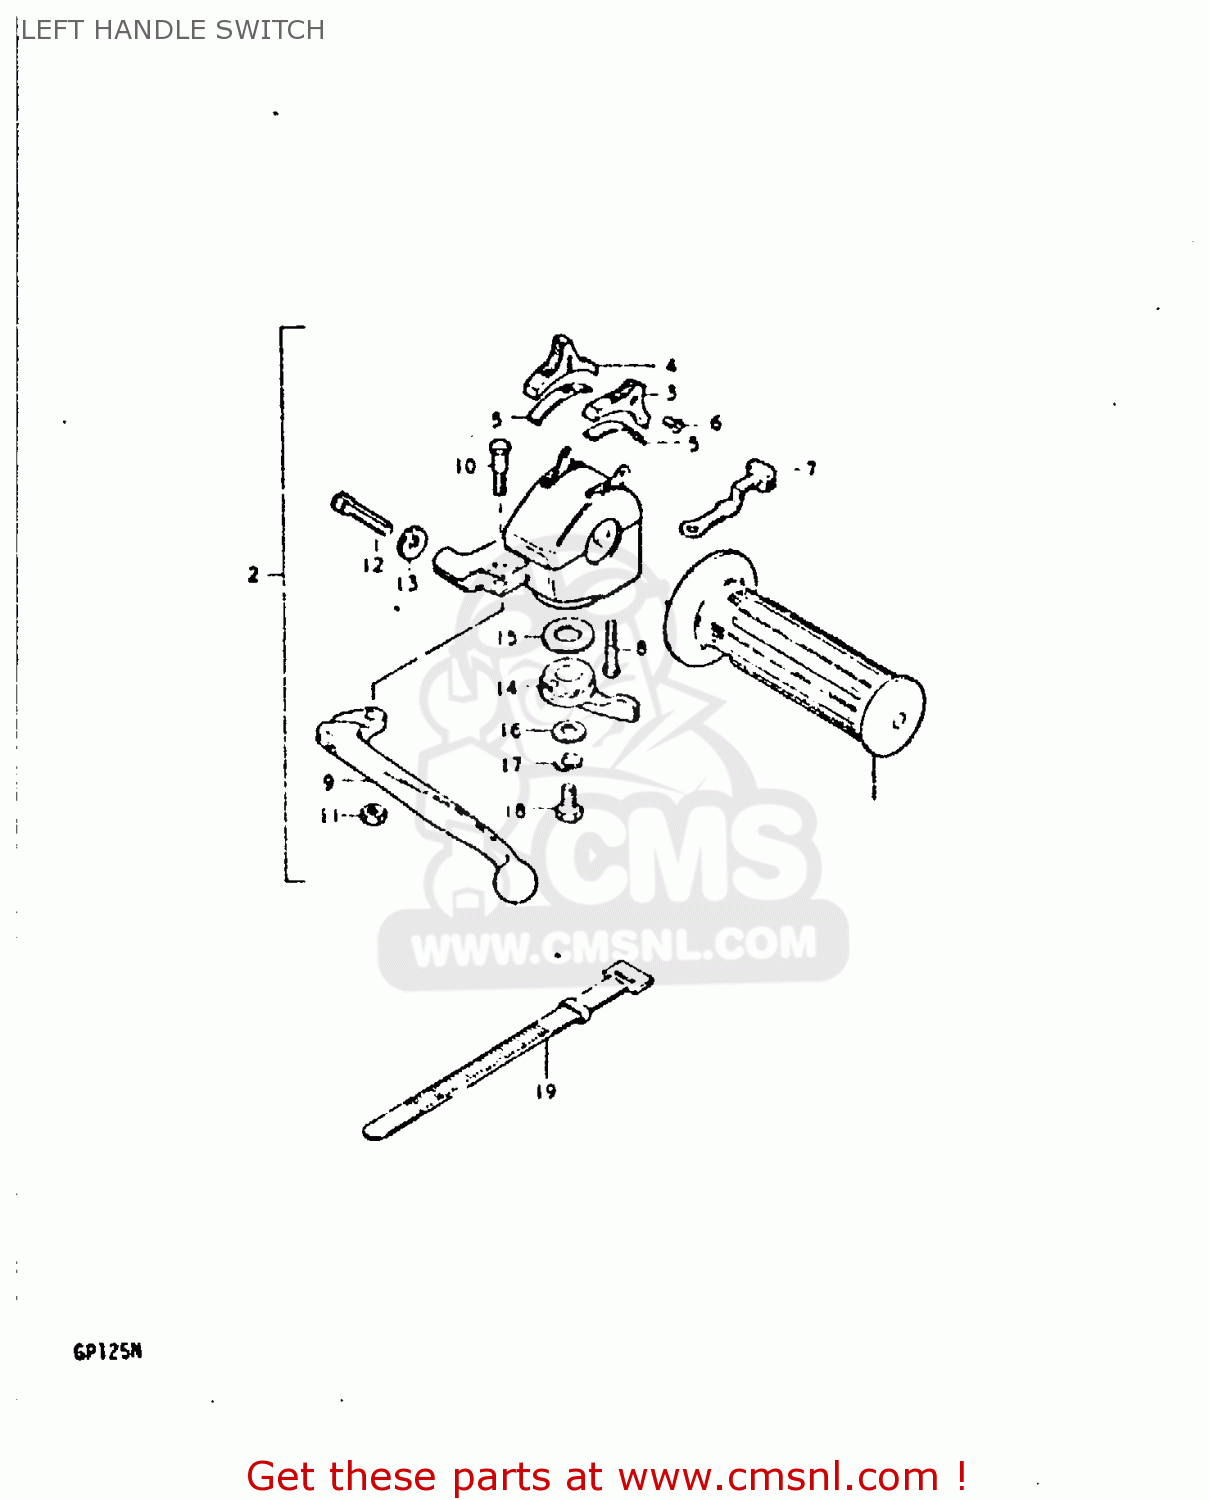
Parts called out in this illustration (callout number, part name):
1	GRIP,L
2	LEVER ASSY,CLUTCH
3	KNOB,HANDLE SWITCH
4	KNOB,HANDLE SWITCH
5	PLATE,SWITCH KNOB
6	SCREW
7	LEVER,TURN SIGNAL
8	SCREW 5X20
9	LEVER,CLUTCH
10	BOLT
11	NUT 6MM
12	ADJUSTER,CABLE
13	NUT,CABLE ADJUSTER
14	LEVER,STARTER
15	WASHER,ADJUSTER
16	WASHER,STARTER LEVER
17	LOCK WASHER
18	BOLT
19	CLAMP(L:120)
